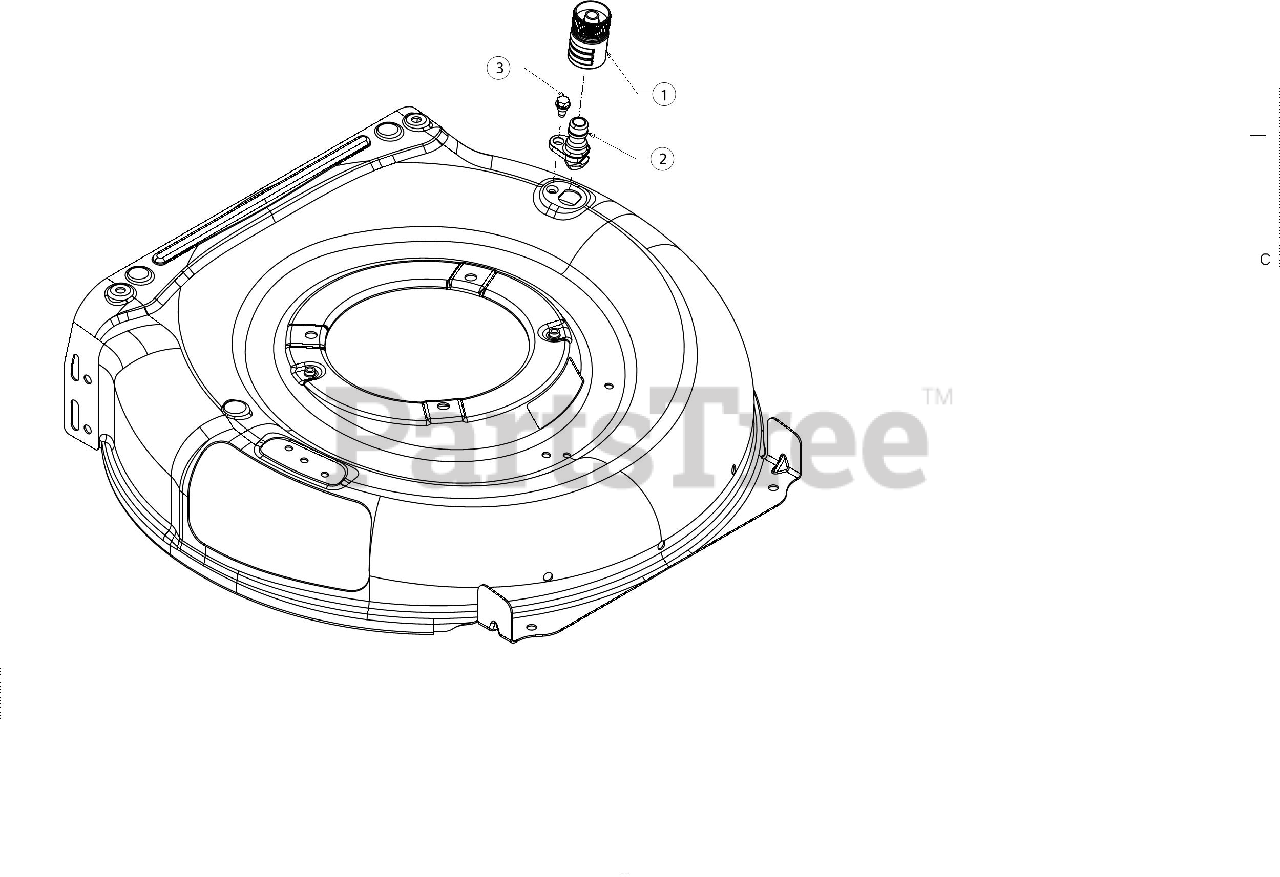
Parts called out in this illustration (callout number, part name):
1	WATER NOZZLE
2	DECK WASH NOZZLE
3	SHOULDER SCREW 1/4-20 X .50
